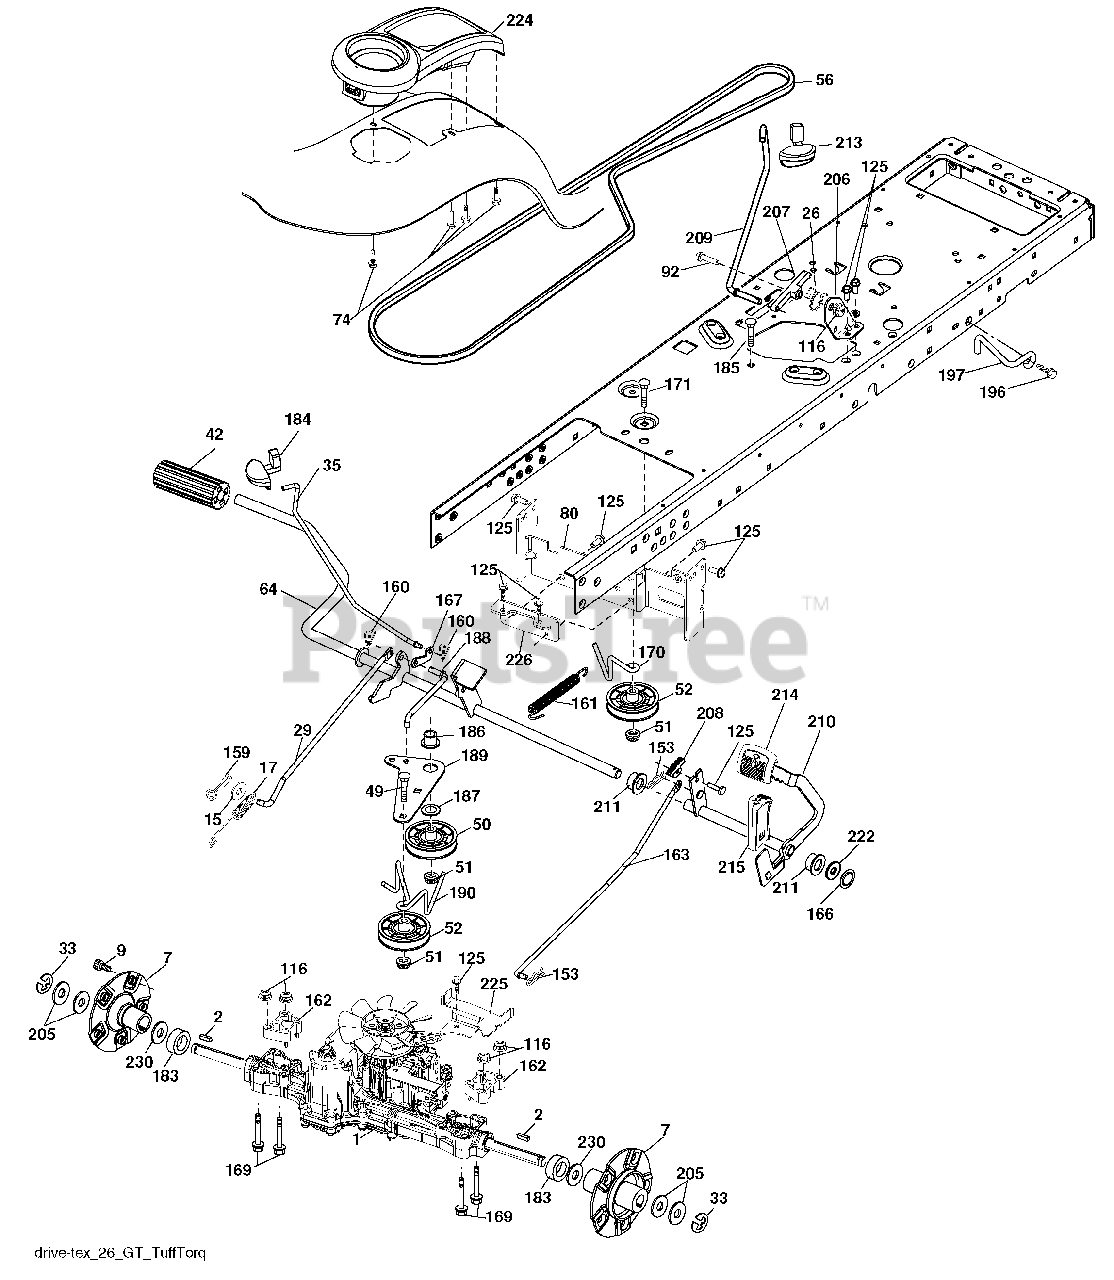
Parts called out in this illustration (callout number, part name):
2	Key
7	Hub Asm. Wheel
9	Bolt Hub Wheel
15	Washer 13/32 x 13/16 x 16 Ga.
17	Spring, Brake
26	Spring Return Cruise
29	Rod, Brake
33	Ring E
35	Rod, Brake, Park
42	Cover, Foot Pedal
49	Bolt
50	Pulley Idler Flat
51	Lock Nut 3/8-16
52	Idler V-Groove 910" Offset
56	V-Belt, Drive
64	Shaft Asm. Pedal Brake Control
74	Screw Hx Wsh Hi-Lo 1/4 x 1/2 unc
80	Strap Torque
92	Bolt Fin Hex 5/16-18 unc x 1.25
116	Nut Lock Hex Flange 5/16-18
125	Screw 5/16-18 x 3/4
153	Retainer Spring
159	Pin Cotter 1/8 x 3/4
160	Retainer Clip
161	Spring, Return, Clutch
162	Spacer Transaxle
163	Rod Pedal Control
166	Nut Push .625
167	Latch Brake Parking
169	Bolt 5/16-18 x 3.75
170	Keeper Belt Centerspan
171	Bolt
183	Spacer Split
184	Handle Parking Brake
185	Bolt
186	Spacer Retainer
187	Washer
188	Link Clutch Ground Drive
189	Bellcrank Ground Drive
190	Keeper Bellcrank Ground Drive
196	Screw 3/8-16 x 1
197	Bracket Clutch Anti-Rotation
205	Washer
206	Bracket Mount Latch Cruise
207	Latch Control Cruise
208	Bolt Sector Control Cruise
209	Rod Conrtrol Cruise
210	Rocker Asm. Pdeal Control
211	Bearing Nylon
213	Knob Control Cruise
214	Pad Pedal Forward
215	Pad Pedal Reverse
222	Washer 21/32 x 1-1/4 x 10 Ga.
224	Console Toolbox
225	Keeper Belt Trans.
226	Bracket Mount Torque
230	Washr Hardened
